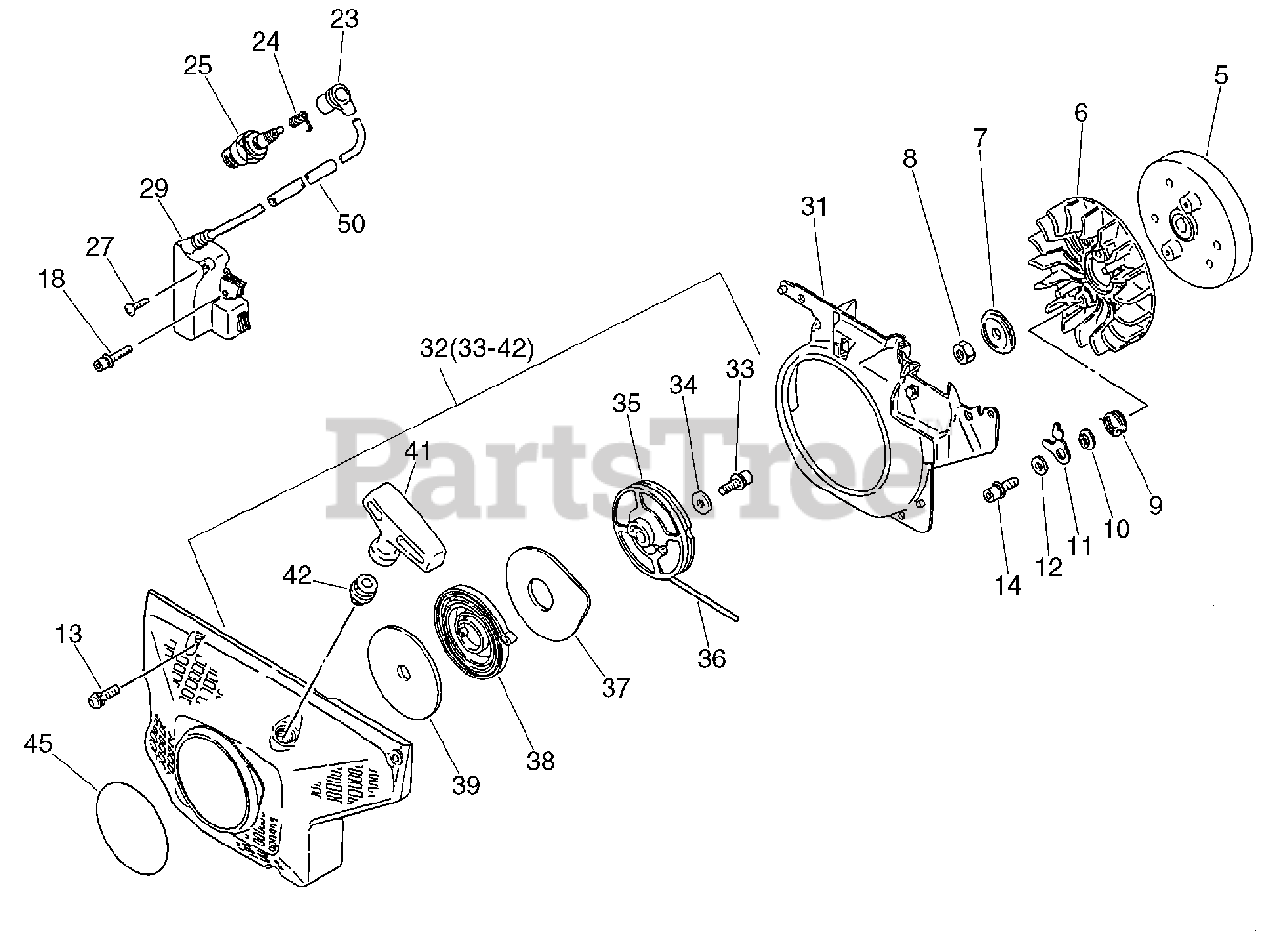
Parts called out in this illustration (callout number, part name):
5	FLYWHEEL
7	WASHER 8.2×31×0.8
9	SPRING, RETURN
10	SPACER, PAWL
11	PAWL, STARTER
12	WASHER 5.5×12×0.8
13	SCREW 5×20
14	BOLT 5×14
18	BOLT 4×20
23	CAP, SPARK PLUG
24	TERMINAL, SPARK PLUG
25	SPARK PLUG - RCJ6Y
27	SCREW 4×8
29	COIL, IGNITION
31	COVER, FAN
32	STARTER ASSY
33	BOLT 5×14
34	WASHER 5.5×12×0.8
35	REEL, ROPE
36	ROPE, STARTER 4.0×950
37	PLATE, STARTER
38	SPRING, RECOIL
39	PLATE, STARTER
41	GRIP, STARTER
42	GUIDE, ROPE
45	LABEL - ECHO
50	TUBE, INSULATOR
